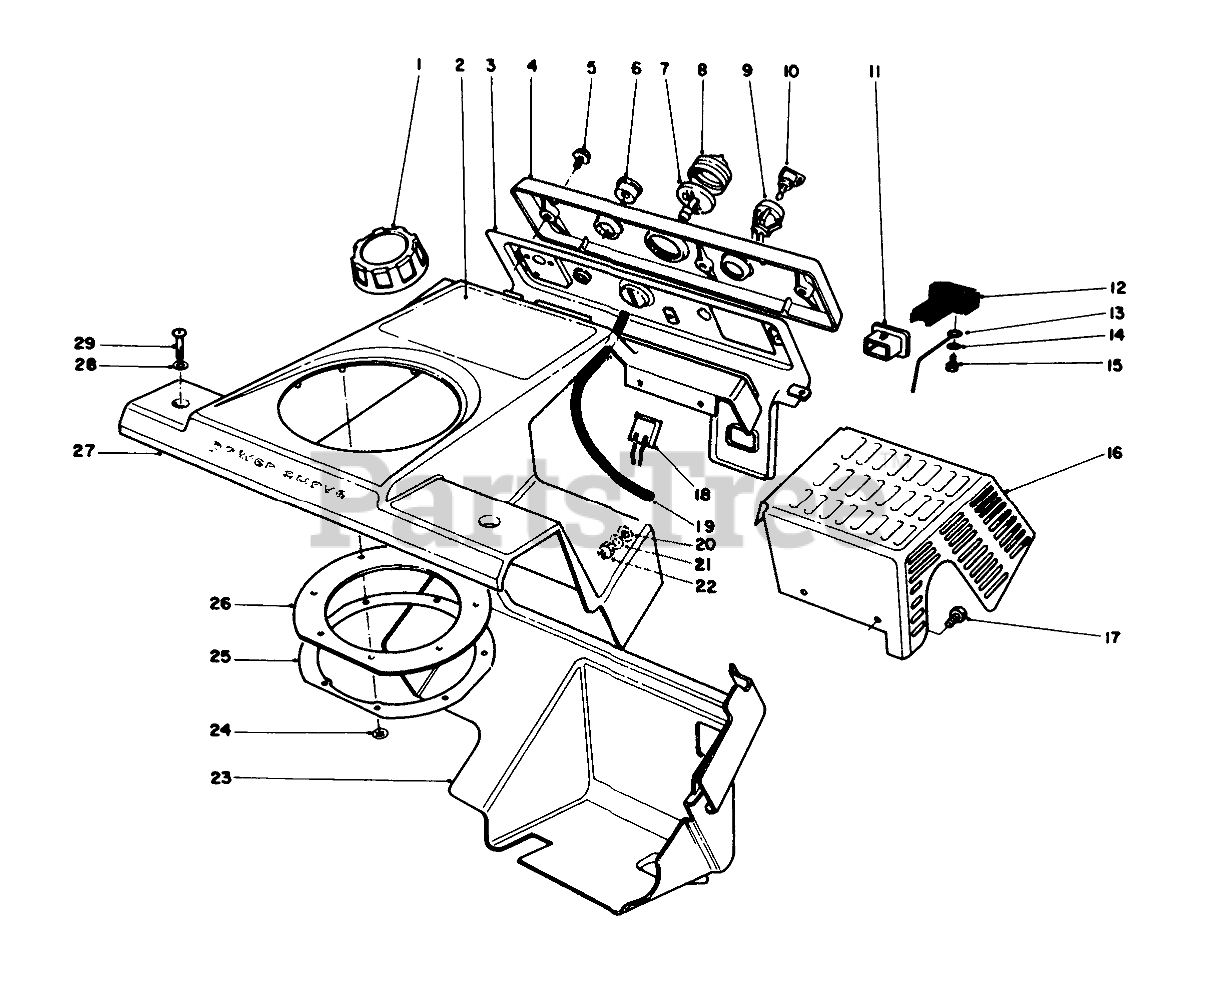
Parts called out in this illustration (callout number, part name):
1	CAP-FUEL ASM
2	DECAL - CCR 2000
3	Control Panel Assembly (Incl. Ref. #6-8 & 11)
4	CONTROL NAMEPLATE
5	SCREW-HWH
6	GUIDE-ROPE, STARTER
7	BODY-PRIMER
8	BULB-PRIMER
9	SWITCH
10	KEY-IGNITION
11	FITTING
12	CONTROL-CHOKE
13	Unkage-Choke
14	WASHER-PLAIN
15	SCREW-PPH
16	Wa-Shield
17	SCREW-SHH
18	CONNECTOR-BODY
19	PRIMER HOSE
20	WASHER
21	WASHER-FLAT
22	NUT-LOCK, NI
23	Shroud-Lower
24	PALNUT
25	Retainer-Chute Seal
26	SEAL-CHUTE
27	Upper Shroud Assembly (Incl. Ref. #2 & 24-26)
28	WASHER-FLAT
29	SCREW-PPH
